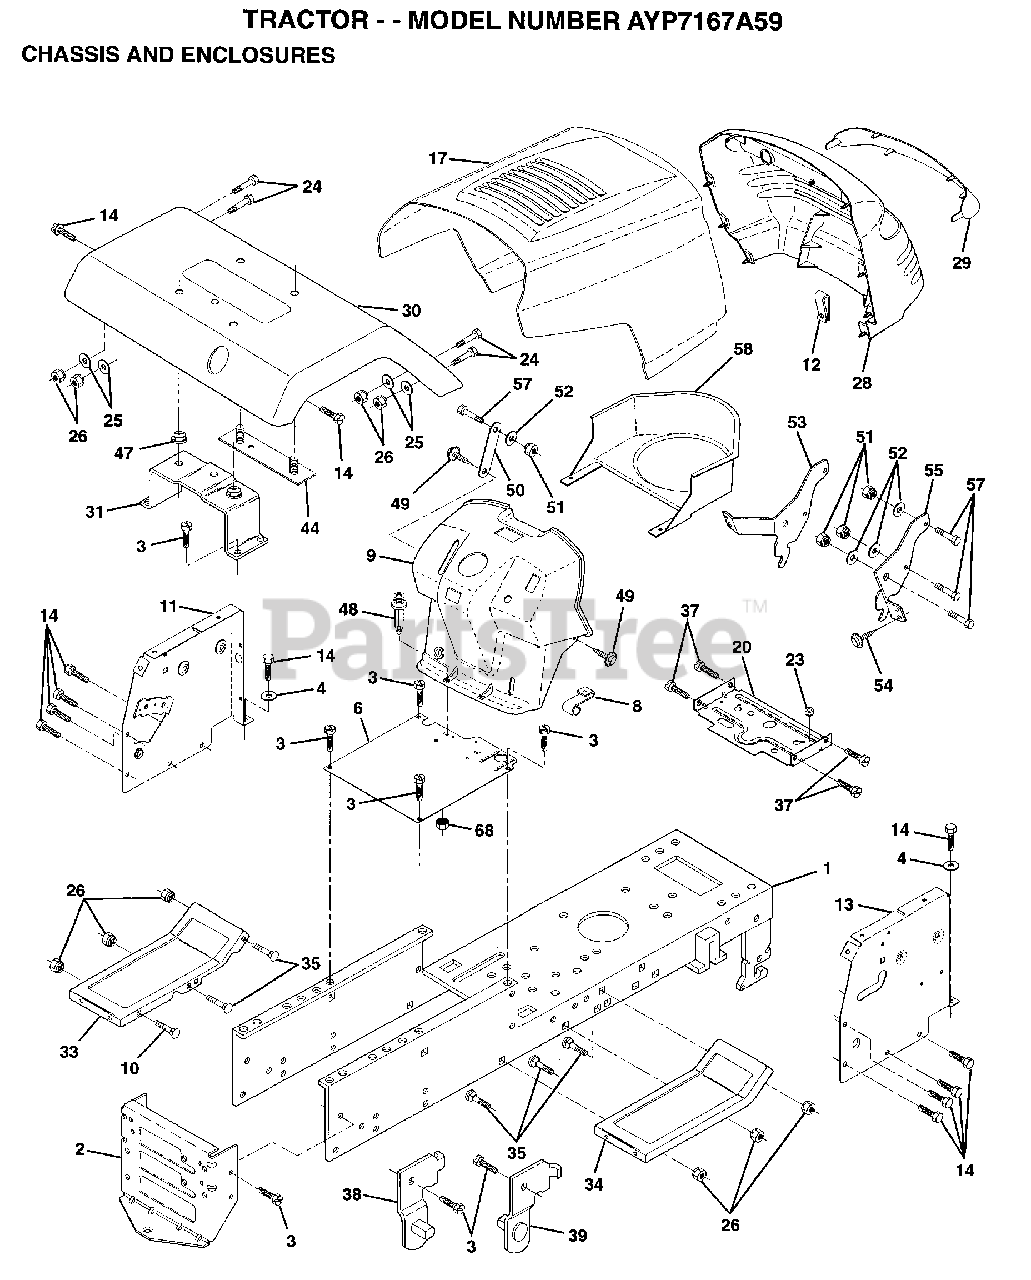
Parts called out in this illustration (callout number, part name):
1	CHASSIS.WLD.11GA
3	SCREW
4	WASHER
8	"CLIP,INSULATOR"
11	PANEL ASM DASH
12	CLIP.TINNERMAN
14	SCREW LT
17	HOOD.STL.PRV.LB
20	PLATE.MTG.BTRY.TK
24	BOLT
25	WASHER
26	NUT
29	LENS GRILLE
31	BRKT.ASM.FENDER
33	FOOTREST.LT.LT/GT
34	FOOTREST.RH.LT/GT
35	BOLT
37	SCREW TI
38	BRACKET ASM LH
39	BRACKET ASM RH
44	STRAP ASM FENDER
47	NUT-PUSH YT
48	RIVET.PUSH.PLATE
49	SCREW HEX CRT
50	BRACE SUPT DASH
51	NUT
52	WASHER
53	BRACKET.GRILLE.LH
55	BRACKET.GRILLE.RH
58	DUCT AIR 12-15H
68	NUT
